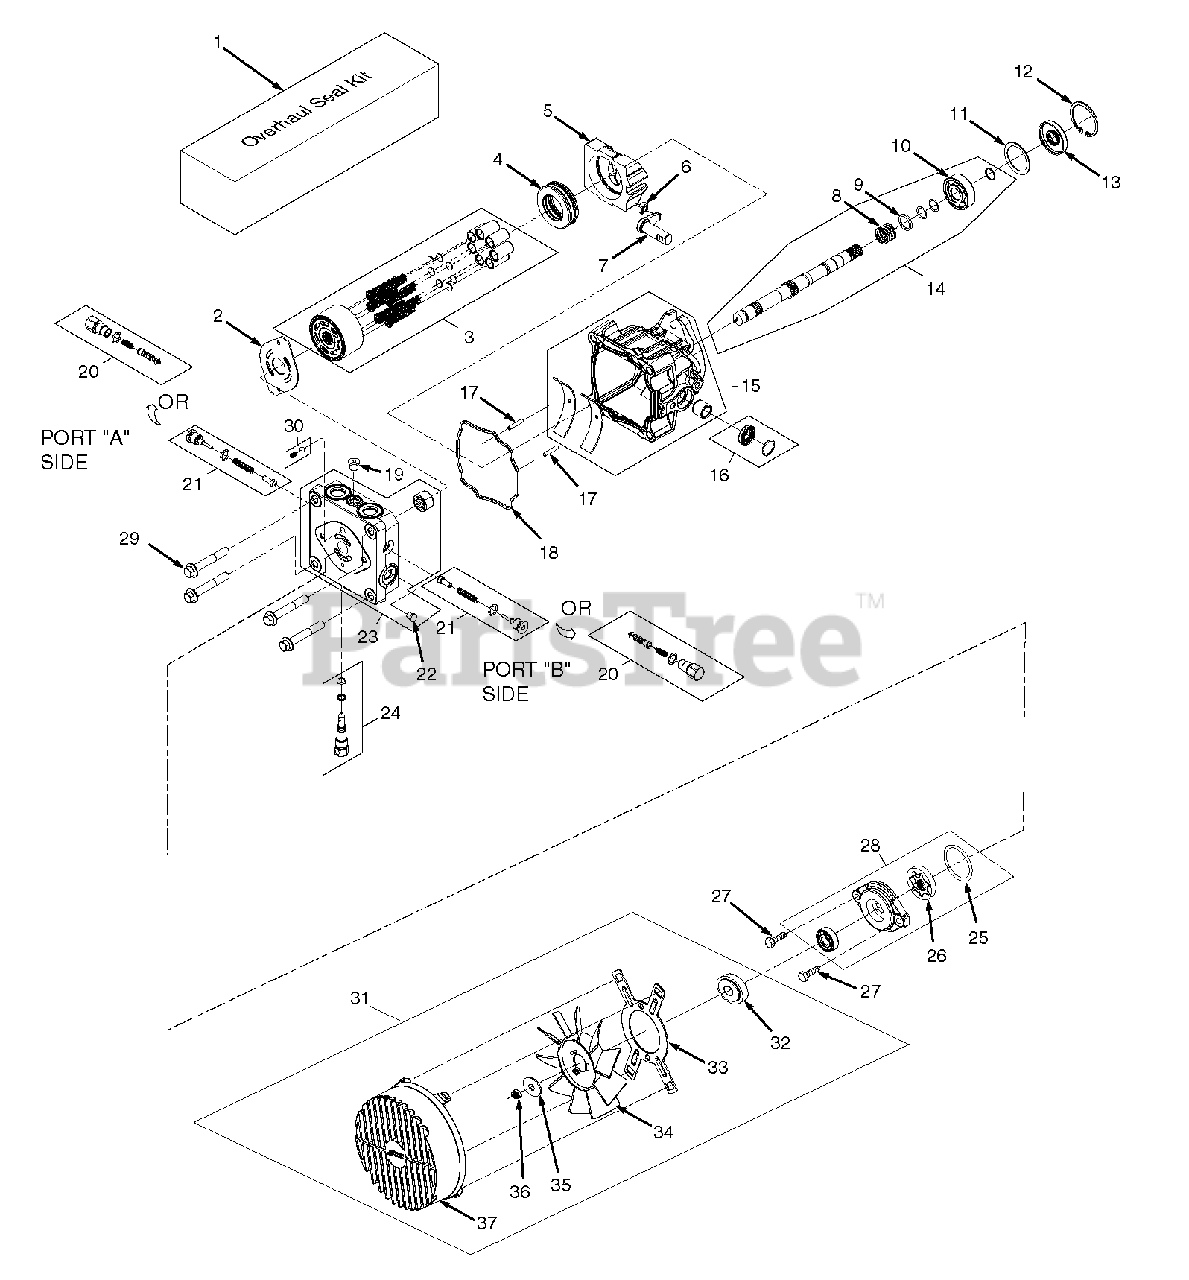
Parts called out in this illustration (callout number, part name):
1	Overhaul Seal Kit
2	Valve Plate
3	Cylinder Block Kit - 16cc
4	Thrust Ball Bearing Assembly
5	Variable Swashplate
6	Slot Guide
7	Trunnion Arm
8	Block Spring
9	Block Thrust Washer
10	Shaft Ball Bearing
12	Retaining Ring
14	Kit, Pump Shaft
15	Housing Kit
16	Trunnion Seal Kit
18	O-Ring
19	Straight Thread Plug
20	Shock Valve Kit
21	Shock Valve Kit
22	Straight Thread Plug
23	End Cap Kit
24	Bypass Valve Kit
26	Gerotor Assembly (.19 cu.in./rev.)
27	Socket Head Cap Screw (M8 x 1.25-25mm)
28	Charge Pump Kit (.19 STD. Splined)
29	Hex Screw, Flng. Head (M10 x 1.50-65mm)
30	Charge Relief Kit
31	Fan Kit
33	Bracket, Shroud
35	Washer
37	Shroud
